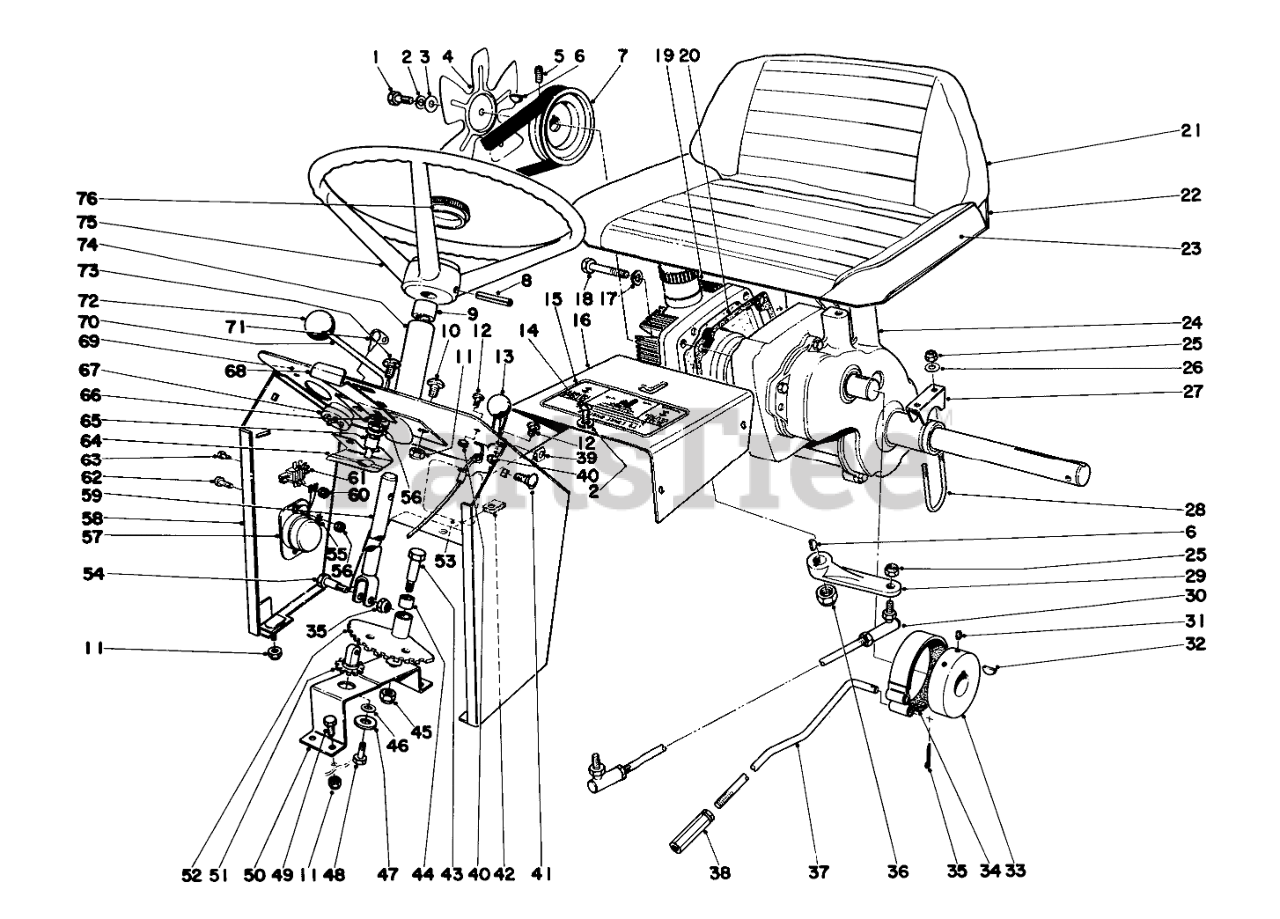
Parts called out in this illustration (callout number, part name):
1	SCREW-HH
2	WASHER-LOCK
3	WASHER-FLAT
5	SCREW-SET, HSH
6	KEY-WOODRUFF
7	Pulley
8	PIN-ROLL
9	BUSHING
10	Round Head Screw
11	NUT-LOCK, CONE
13	Throttle Control
14	SCREW
15	Decal
16	Tunnel
17	WASHER-LOCK
18	SCREW-HH
19	Hydrostatic Transmission
20	Gasket
21	Seat Back
22	Frame-Seat
23	Seat Cushion
24	Transaxle
25	NUT-HEX
26	WASHER-FLAT
27	Axle Bracket
28	U-Bolt
29	Lever Hydrostatic
30	Control Rod Transmission
31	SCREW-SET
32	KEY-WOODRUFF
33	Brake Drum
34	Brake Band
35	PIN-COTTER
36	NUT-LOCK, CONE
37	Brake Rod Rear
38	Screw Brake Adjusting
39	Strap Cable Tie
40	NUT-KEPS
41	BOLT-CARR
42	SPEED NUT
43	Shoulder Bolt
44	BUSHING
45	NUT-LOCK
46	Spacer
47	Washer
48	SCREW-HH
49	SCREW-HH
50	Bracket
51	Pinion Steering
52	Gear Steering (Incl. Ref. #44)
53	Decal-Caution
54	Screw Shoulder
55	WASHER-LOCK/EXT
56	NUT-LOCK, CONE
57	Cover-Center
59	Steering Shaft
60	NUT-LOCK, NI
61	Terminal Block
63	SCREW-HEAD, PAN
64	Spring Detent
65	BUSHING
66	WASHER-FLAT
67	STARTER SWITCH
68	Hood Latch
69	Decal-Dash
70	Handle Hydrostatic Control (Incl. Ref. #65)
71	Key
72	Knob
73	Carriage Bolt
74	Steering Tube (Incl. Ref. #9)
75	Steering Wheel
76	Steering Wheel Cap
